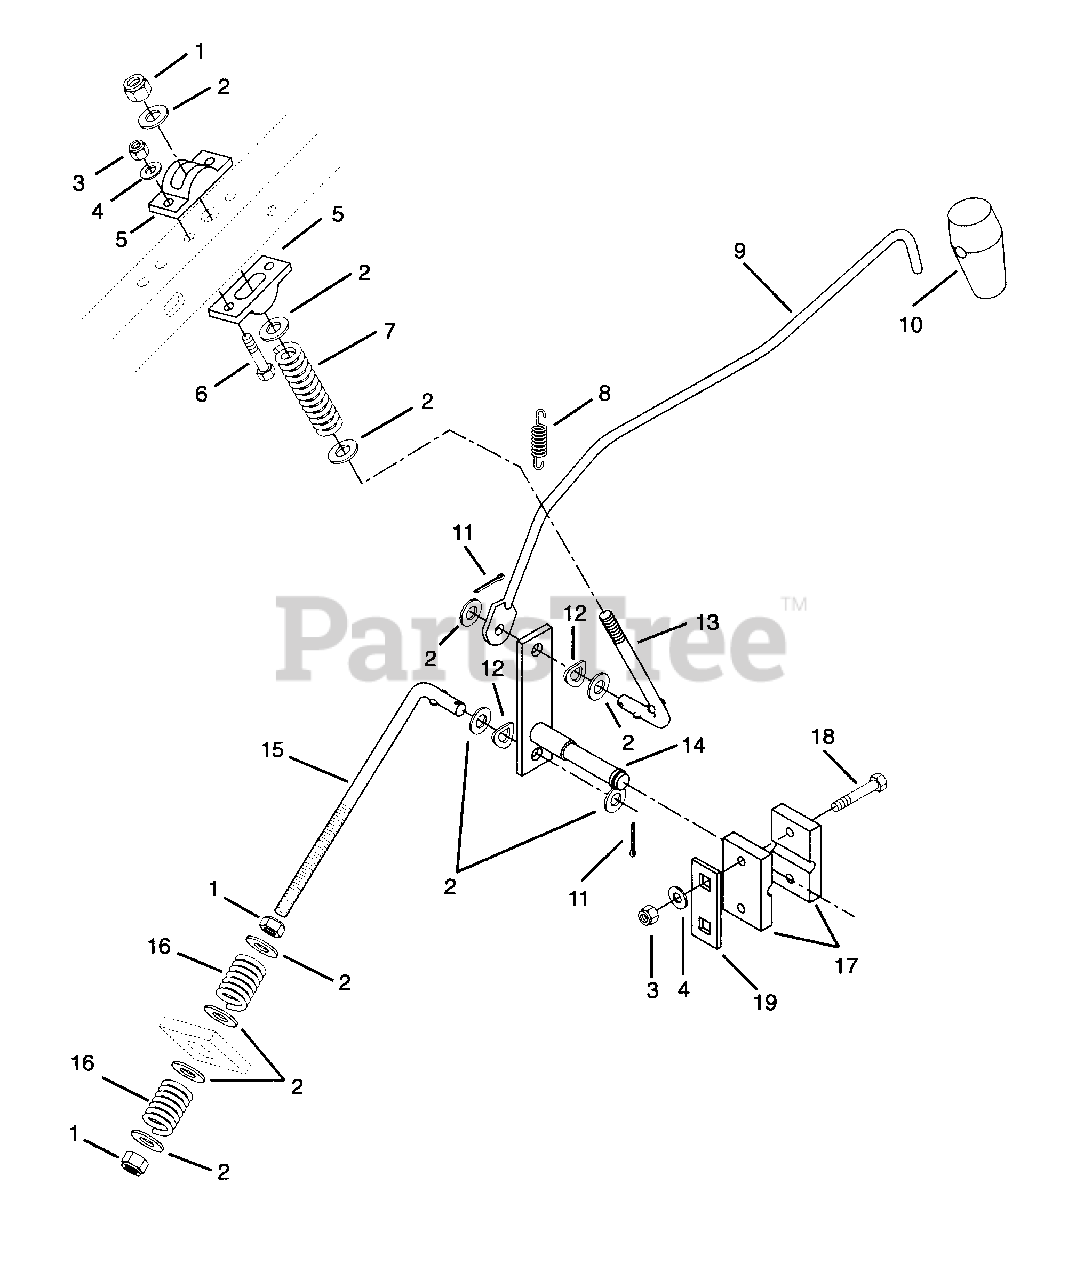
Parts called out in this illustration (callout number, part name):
1	Nut-Locking-Center .375-16 Grade 2
2	Washer-Flat-Steel .406 x .812 x .065
3	Nut-Locking-Center .250-20 Grade 2
4	Washer-Flat-Steel .281 x .620 x .065
5	Cam, Shifter
6	Bolt-Hex .25-20 x 1.00 Grade 5
7	Spring-Compression .081 x .720 x 2.75
8	Spring-Tension .041 x 1.25 x .50
9	Rod, Shifter
10	Handle, Rubber Shifter
11	Pin-Cotter .12 x .75
12	Spring Washer
13	Link, Shifter Stop
14	Weldment, Shifter Crank
15	Link, Shifter
16	Spring-Compression .125 x .78 x 1.00
17	Block, Shift Lever
18	Bolt-Hex .25-20 x 1.50 Grade 5
19	Shim, Mower Height Adjuster Bracket
